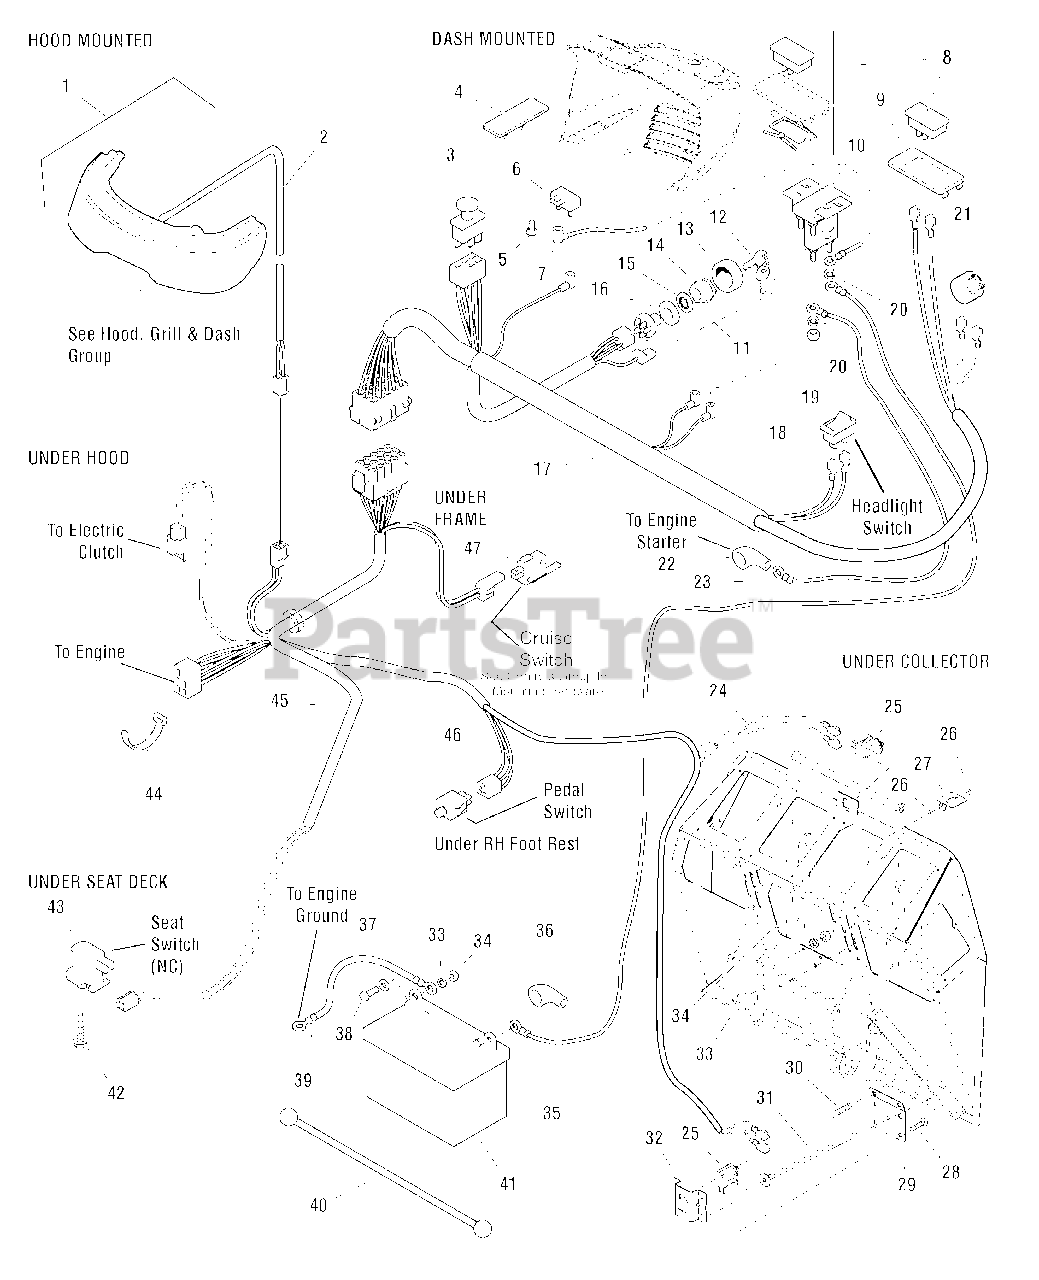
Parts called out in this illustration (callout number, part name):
1	HEADLIGHT ASSEMBLY
2	HARNESS, Headlight Assembly
3	SWITCH, PTO, Push/Pull
4	PLUG, Hole
5	CAPSCREW, Hex Head, 1/4 x 5/8
6	BREAKER, Circuit 12Volt, 20Amps
7	WIRE, 12GA, 5.9" Long, Red
8	METER, Hour, Digital, Early Models
8	METER & CLIP, Hour, Digital, Later Models (Includes Ref. No.
9	PLUG, Dash, Hour Meter, Early Models
9	PLUG, Dash, Hour Meter, Later Models
10	SOLENOID
11	SWITCH ASSEMBLY, Ignition, 6 Pin, (Includes Ref. Nos. 12, 13
12	KEY, Ignition
13	COVER
14	NUT, Hex Flange, 5/8-32
15	LOCKWASHER, Internal Tooth, 5/8
16	WASHER
17	HARNESS, Wiring Upper, Early Models (Use with Hour Meter 172
17	HARNESS, Wiring Upper, Later Models (Use with Hour Meter Kit
18	SWITCH, Headlights , 2 Terminal
19	NUT, Hex, 5/16-24
20	LOCKWASHER, External Tooth, 5/16
21	BUZZER, Pulse, Bag Full
22	BOOT, Insulator
23	CABLE, # 6, 25" Long, Red
24	HARNESS, Wiring, Rear
25	SWITCH, Push Button, Black
26	O - RING
27	PAD, Actuator
28	CAPSCREW, Hex Head Taptite, 1/4-20 x 1/2
29	BRACKET, Switch
30	CARRIAGE BOLT, 1/4-20 x 5/8
31	ROD & WASHER ASSEMBLY, Hopper
32	BRACKET, Hopper Switch
33	LOCKWASHER
34	NUT, Hex, 1/4-20
35	CABLE, # 6, 9" Long
36	BOOT, Insulator Battery Terminal
37	WASHER
38	CAPSCREW, Hex Head, 1/4-20 x 3/4
39	CABLE, # 6, 26" Long
40	STRAP, Battery
41	BATTERY, 12 Volt
42	SCREW, Hex Washer Head Plastite, 1/4-20
43	SWITCH, Operator Present, NC, Grey
44	TIE, Wire
45	HARNESS, Wiring Lower
46	SWITCH, Push Button Foot, Black
47	SWITCH, Cruise, Grey
